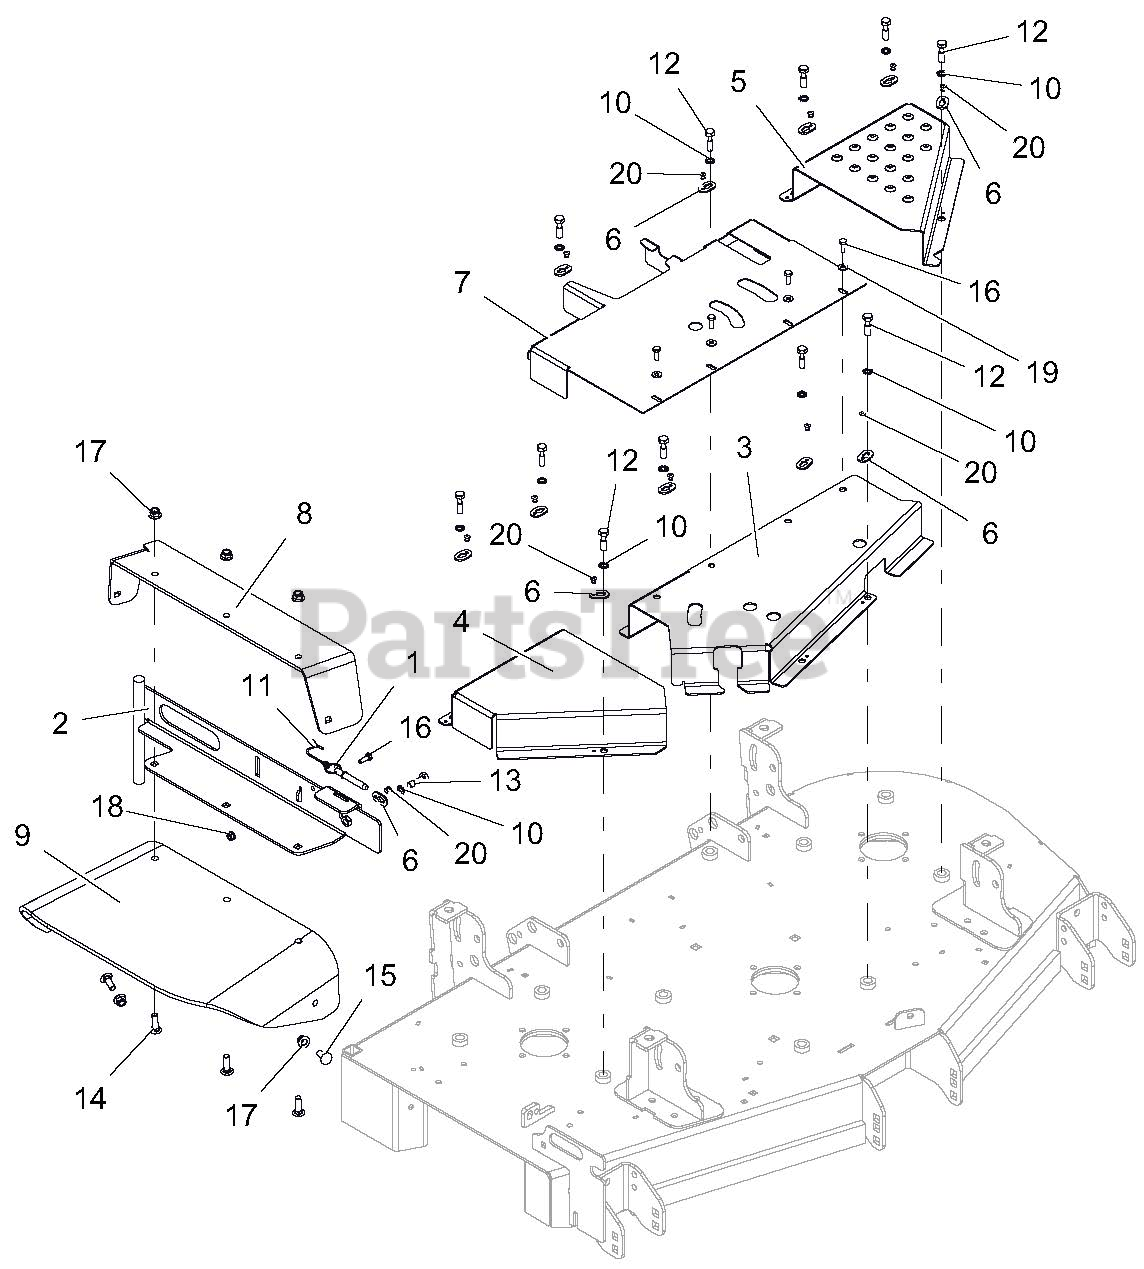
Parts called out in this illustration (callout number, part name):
1	PIN, SPRING BALL .375 OD X 1.50
2	WLDMT, 48" DISCHARGE CHUTE MTG-CE
3	WLDMT, FRONT BELT SHIELD
4	GUARD, RH PT200 CE BELT
5	GUARD, LH PT200 CE BELT
6	KEEPER, BOLT
7	SHIELD, BELT REAR
8	SUPPORT, CHUTE MOUNTING BRACKET-RED
9	CHUTE, RUBBER DISCHARGE
10	LOCK, WSHR-EXT 0.391 X 0.628 X 0.036 YWZC
11	CABLE, 6.0 LANYARD, NYLON
12	BLT, HEX 0.38-16 X 1.25 GR5 CAPTIVE
13	BLT-HEX .38-16X1.25 GR5 CAP .37
14	BLT-RDHDSQNK .38-16X1.25 G5 YWZC
15	BLT-RDHDSQNK .38-16X1.00 G5 YWZC
16	BLT-HEX .25-20X.75 GR5 YWZC
17	NUT-LK-NYL-FLG .38-16 YWZC
18	NUT, LK-TOP-FLG .25-20 YWZC
19	WSHR-FL-STL.281X.62X.065 YWZC
20	RVT-POP .187x.250 (#64) YWZC
